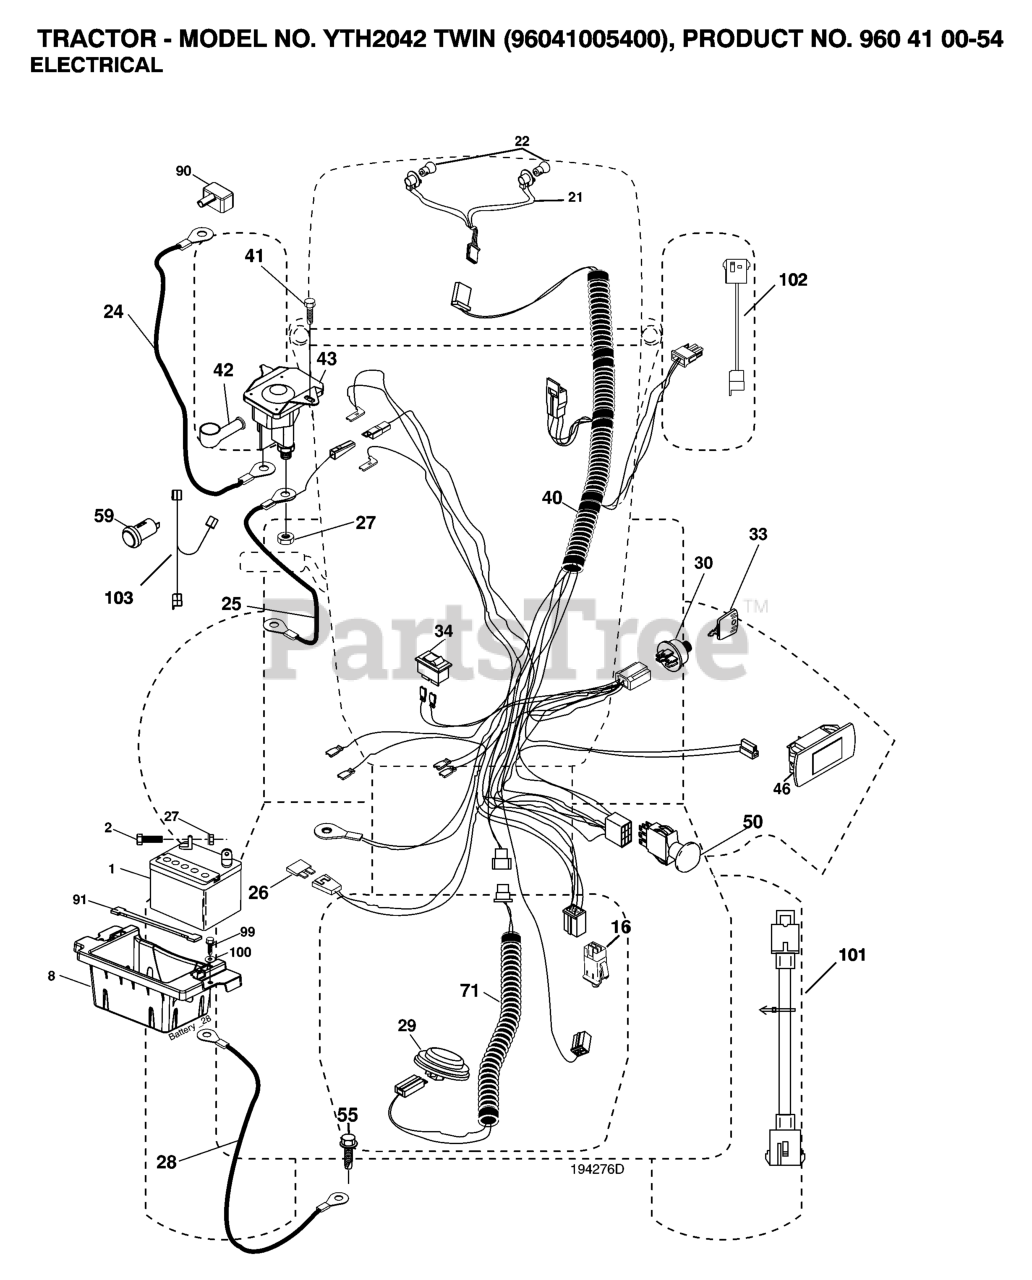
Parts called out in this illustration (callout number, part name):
1	BATTERY 12V .35 AMP
2	BOLT.HEX.1/4.X.3/4.DICHROMATE
8	BOX.BATTERY.MOUNT.FRONT.LT
16	SWITCH INTERLOOK PUSH-IN
21	HARNESS ASSY LIGHT
24	CABLE.BATT.POS.WIRE.TG.DA SOL
25	CABLE.START.RED.17.5".
26	FUSE 20AMP
27	NUT
28	CABLE GROUND 6 GA 21" 90T BLK
29	SWITCH.SEAT.DELTA.OPC.
30	SWITCH.IGN.DELTA.W.LGH.ROS
33	KEY MLD GEN DELTA
40	HARNESS.IGN.DASH.HUQ/P
41	SCREW
42	TERMINAL COVER
43	SOLENOID.W/BRASS.PLUNGER
46	RP.GUAGE.SRVCMNDR.HRMTR.
50	RP.PTO.SWITCH.8 TERMINAL.BLACK
55	SCREW 5/16"
59	OUTLET.12-VOLT
71	HARNESS-CHASSIS SUB
90	COVER.TERMINAL.BATTERY
91	STRAP.BATTERY.MOUNT.FRONT(2 2)
99	SCREW HEXWSHR 1/4-20X3/4
100	WASHER
101	PIGTAIL.MATNLK.NEW.HAR
102	HARNESS PIGTAIL PCH TEX ROS
103	HARNESS PIGTAIL 12V OUTLET
